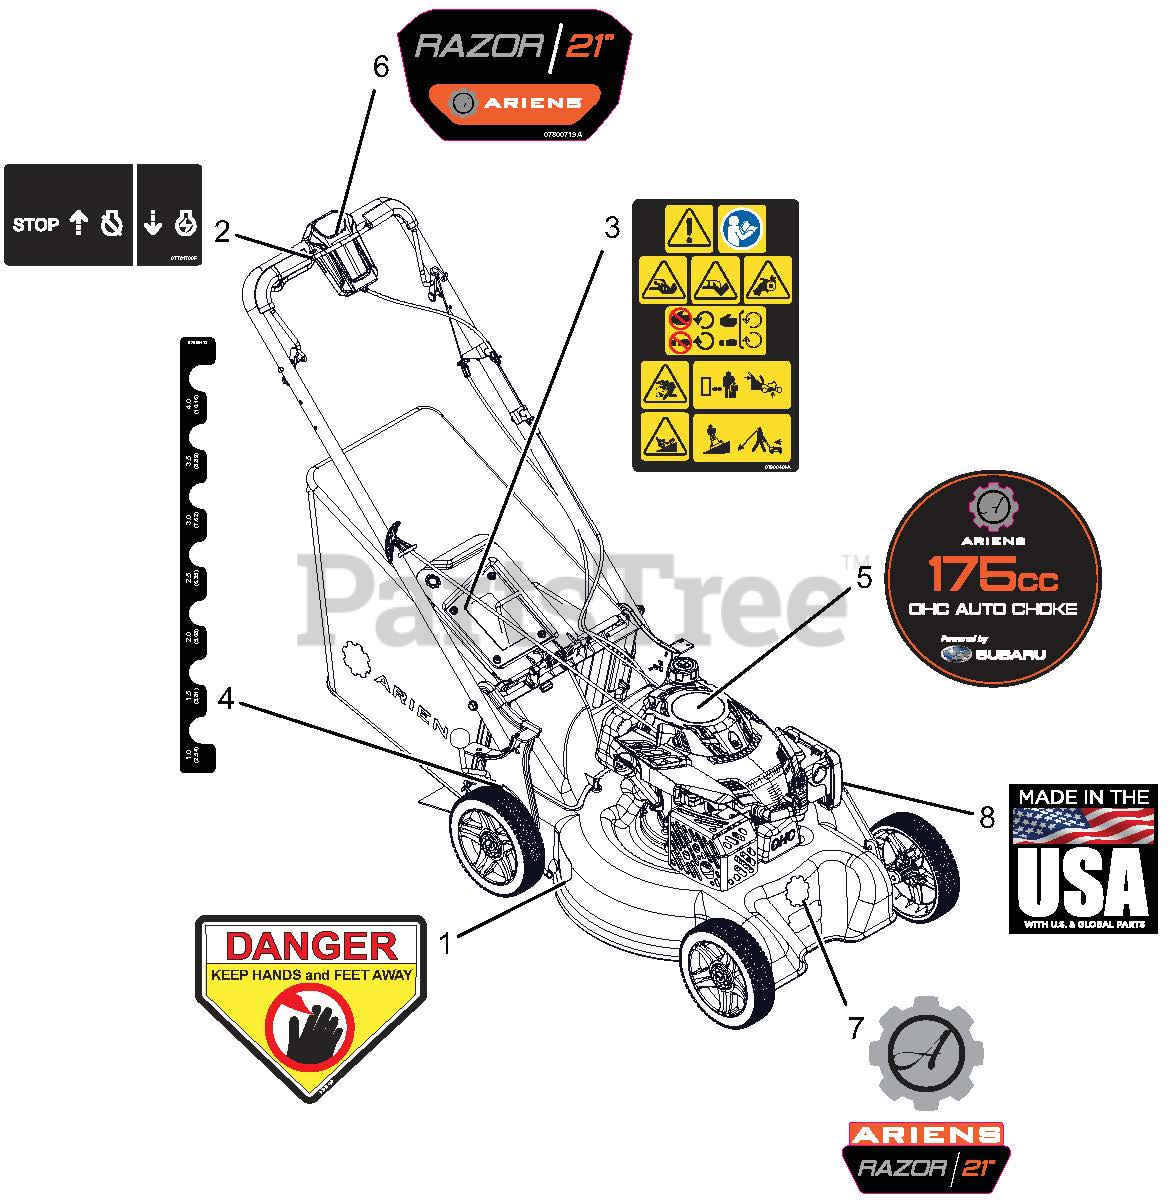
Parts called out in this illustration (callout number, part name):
1	DECAL, DANGER
2	DECAL - ENGINE CONTROL
3	DECAL,MAIN SAFETY_WAW LM
4	DECAL, HOC
5	DECAL-ENGINE STYLE-RAZOR
6	DECAL-CONTROL-RAZOR
7	DECAL-ARIENS RAZOR 21"
8	DECAL, MADE IN USA
